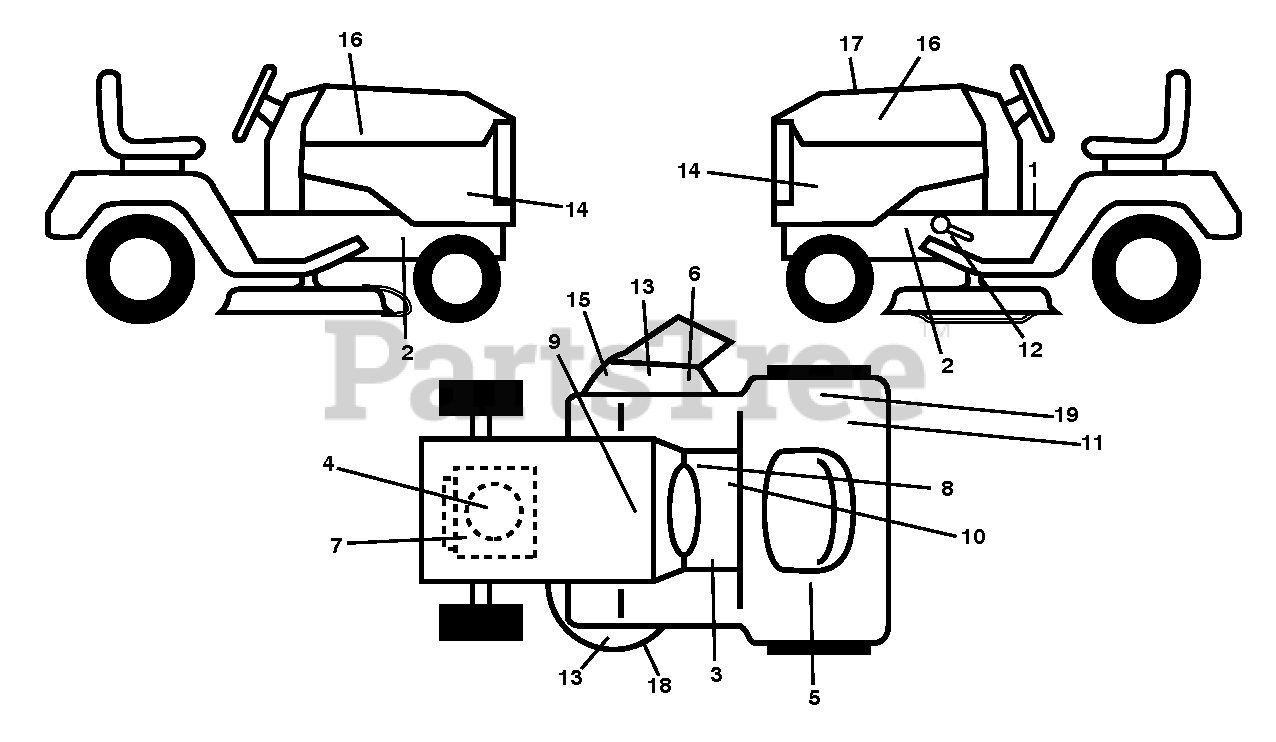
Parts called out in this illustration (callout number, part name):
1	DECAL.READ.OWN.MAN.SYMBOL.LT
2	DECAL.CHASSIS.HOT.MUFFLER
3	DECAL.FNDR.SDLE.BRAKE.CLUTCH.6
4	DECAL.ENG.BS.ENDUR.27HP.382139
5	DECAL.RESERVEFUELSELCTR.ENG
6	DECAL, DECK DEFLECTOR, WARNING
7	DECAL.ENGINE.WARNING
8	DECAL.PARKING.BRAKE.SADDLE.LT
9	DECAL BTRY SYMBOLS
10	DECAL.FWD/REV.PEDAL.SYMBOL
11	DECAL.TICKMARK.6MIL.AUSTRALIA
12	DECAL.PEDAL.HUSQ.CROWN
13	DECAL.DECK.6MIL.EURO.NOSTEP
14	DECAL.SDPNL.GT2.SET.GTH3052TDF
15	DECAL.DECK.6MIL./DEF.SHLD.WARN
16	DECAL.BADGE.170MM.TEXTLOGO.
17	DECAL.RPL.BSM49.ENDR.TGB.52F.
18	DECAL.MOWER.SCH.48/54.PREM
19	DECAL.80.DBA.AUSTRALIA
